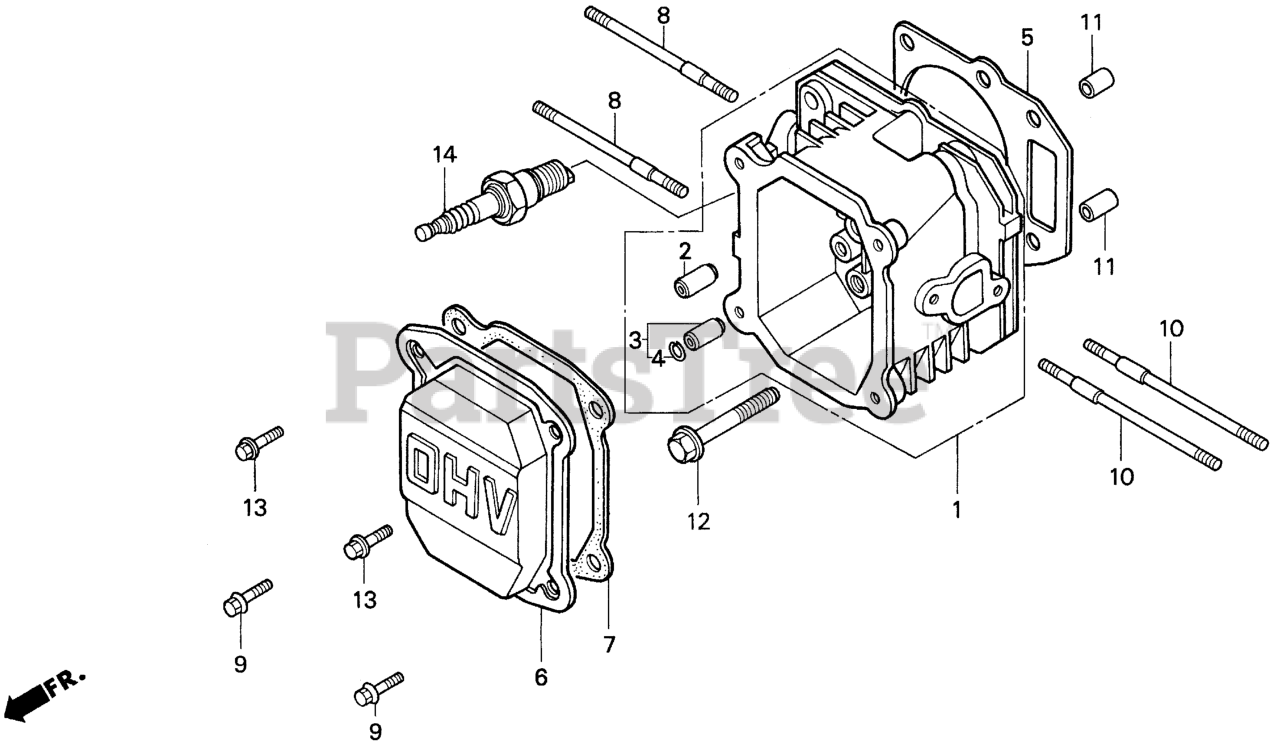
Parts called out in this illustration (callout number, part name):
1	CYLINDER HEAD
1	CYLINDER HEAD (USA)
2	GUIDE, VALVE (OVER SIZE) Use up to Engine SN 2416541.
2	GUIDE, VALVE (OVER SIZE) Use from Engine SN 6324986.
3	GUIDE, EX. VALVE (OS)
4	CLIP, VALVE GUIDE Use from Engine SN 1231803.
5	GASKET, CYLINDER HEAD
6	COVER, HEAD
7	GASKET, CYLINDER HEAD COVER
8	BOLT, STUD (6X83)
9	BOLT, FLANGE (6X13)
10	BOLT, STUD (6X97)
11	PIN A, DOWEL (10X16)
12	BOLT, FLANGE (8X50)
13	BOLT, FLANGE (6X14)
14	SPARK PLUG (BPR4ES) (NGK)
14	SPARK PLUG (W14EPR-U) (DENSO)
14	SPARK PLUG (BP5ES) (NGK)
14	SPARK PLUG (W16EP-U) (DENSO)
14	SPARK PLUG (BP6ES) (NGK)
14	SPARK PLUG (W20EP-U) (DENSO)
